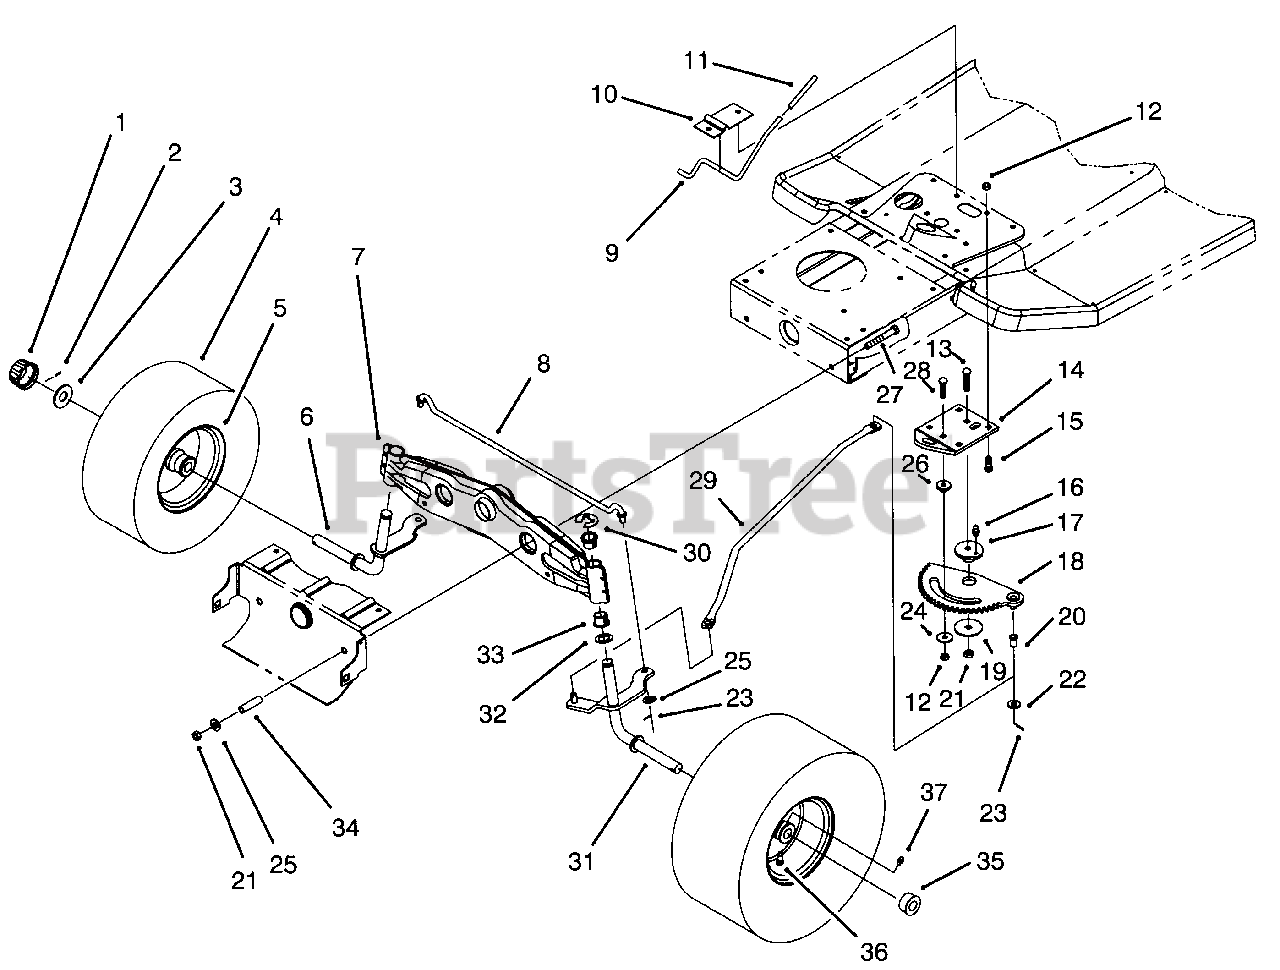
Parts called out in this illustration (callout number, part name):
2	Pin-Cotter
4	Tire-13" (Model No. 81182 Only)
5	Rim-Front Wheel (Model No. 81182 Only)
6	Spindle-R.H.
7	Axle-Front
8	Rod-Steering Tie
9	Rod-Parking Brake
10	Bracket-Parking Brake
11	Grip-Brake Rod
12	Nut-Lock
13	Screw-Carriage
14	Bracket-Steering Rack
15	Bolt-Carriage
16	Fitting-Grease
17	Bushing-Eccentric
18	Rack-Steering
19	Washer-Fender
20	Bushing-Steering Link
21	Nut-Lock
22	Washer-Flat
23	Pin-Cotter
24	Washer-Fender
25	Washer-Flat
26	Spacer-Steering Rack
27	Screw-Hex Hd. Cap
28	Screw-Carriage
29	Link-Drag
31	Spindle-L.H.
32	Washer-Thrust
33	Bushing-Steering Spindle
34	Spacer-Front Axle
35	Bearing-Wheel
36	Valve Stem w/Cap
37	Fitting-Grease
